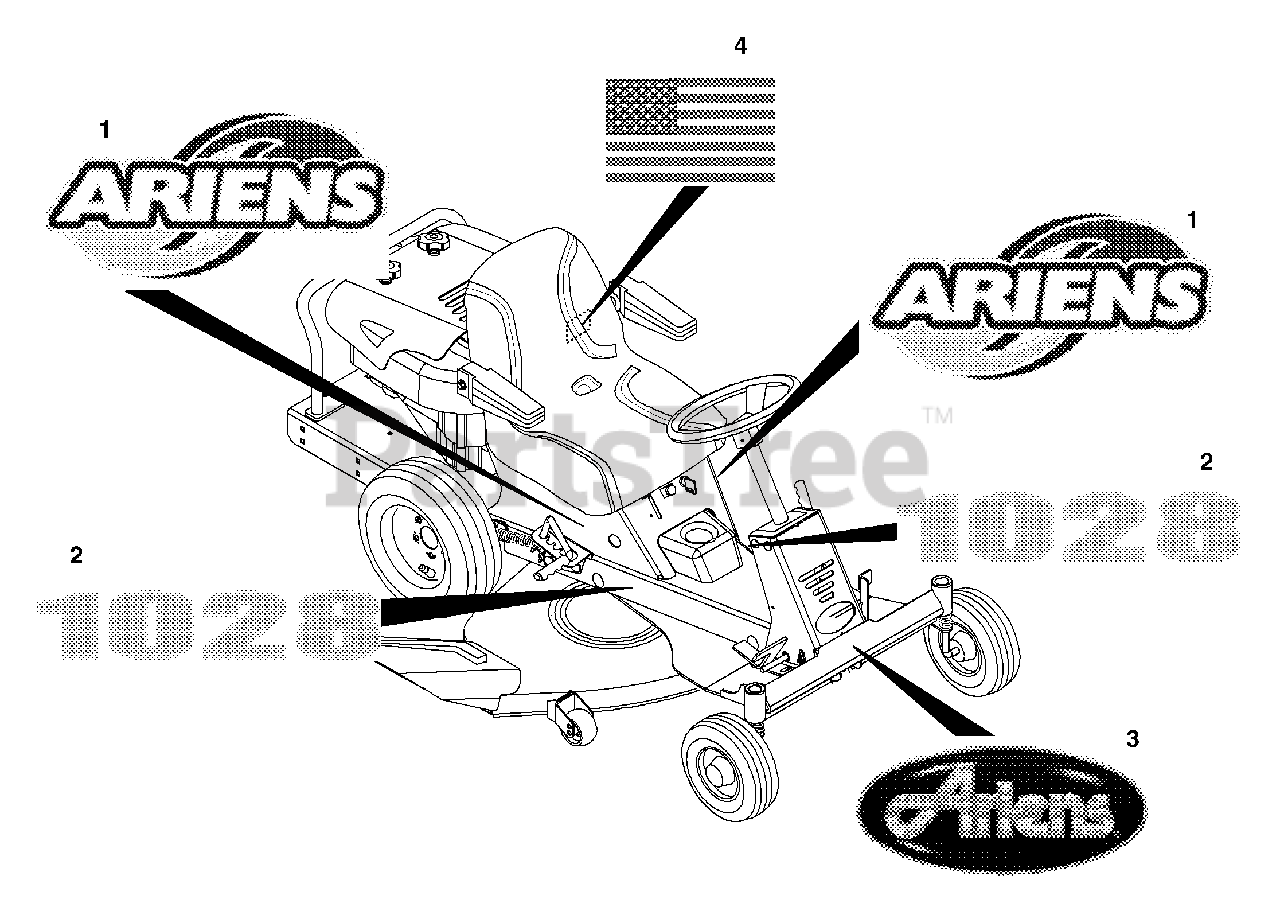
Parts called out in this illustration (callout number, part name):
1	DECAL-ARIENS ZOOM
2	DECAL-1028 RER ARIENS
3	DECAL-ARIENS JEWEL
4	DECAL, AMERICAN FLAG
